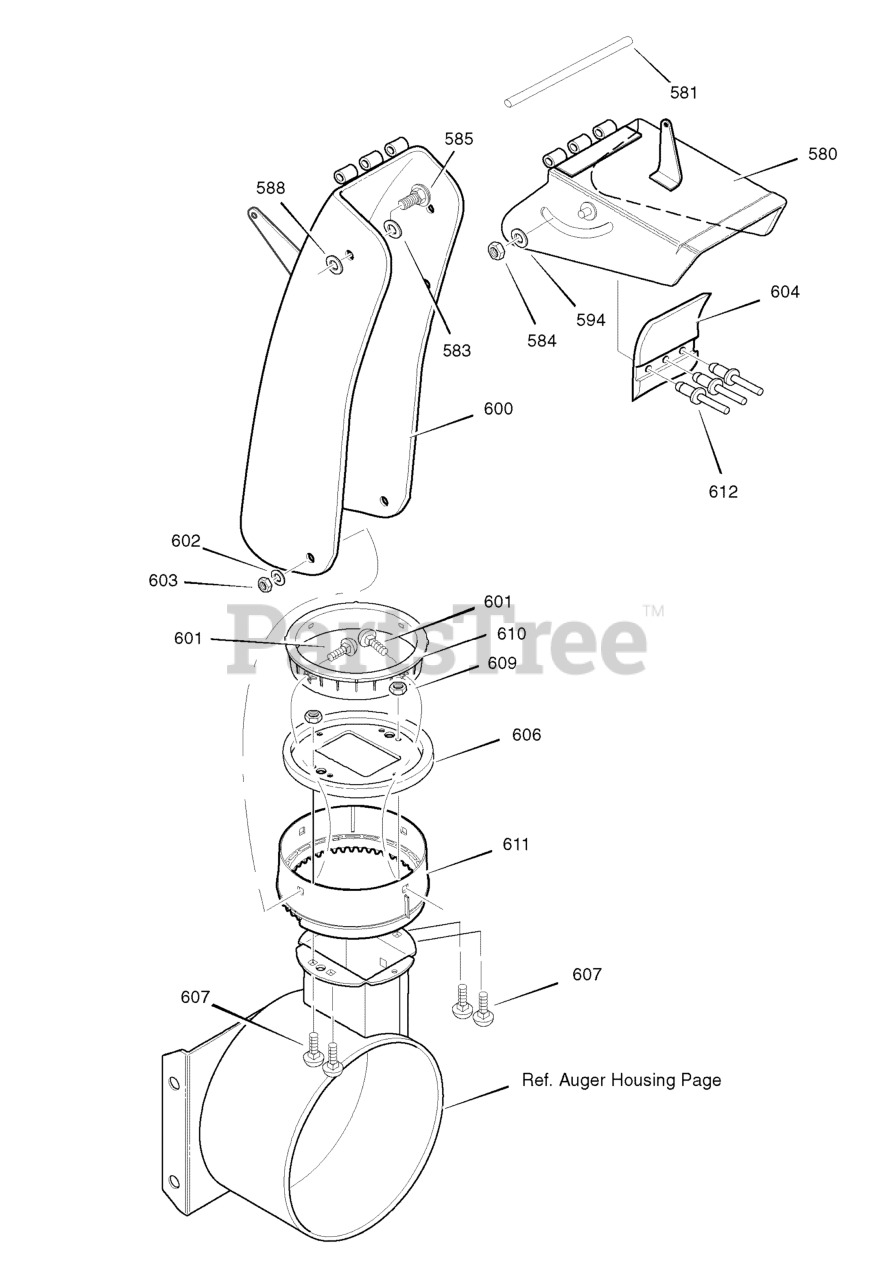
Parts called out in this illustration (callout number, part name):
580	CHUTE, UPPER
581	PIN, HINGE
583	WASHER, PLASTIC
584	NUT, 5/16-18 REGHEX NYLOCK
585	SCREW, 5/16-18 x 0.75
588	WASHER, PLASTIC
594	WASHER, FLAT
600	CHUTE, LOWER
601	BOLT, 5/16-18 X 1.00
602	WASHER, FLAT
603	NUT, 5/16-18 HEXNYL
604	FLAP, CHUTE
606	CHUTE COLLAR
607	SCREW, 1/4-20 X 0.75
609	NUT, 1/4-20 HEX NYLOCK
610	RETAINER RING INNER
611	RETAINER RING OUTER
